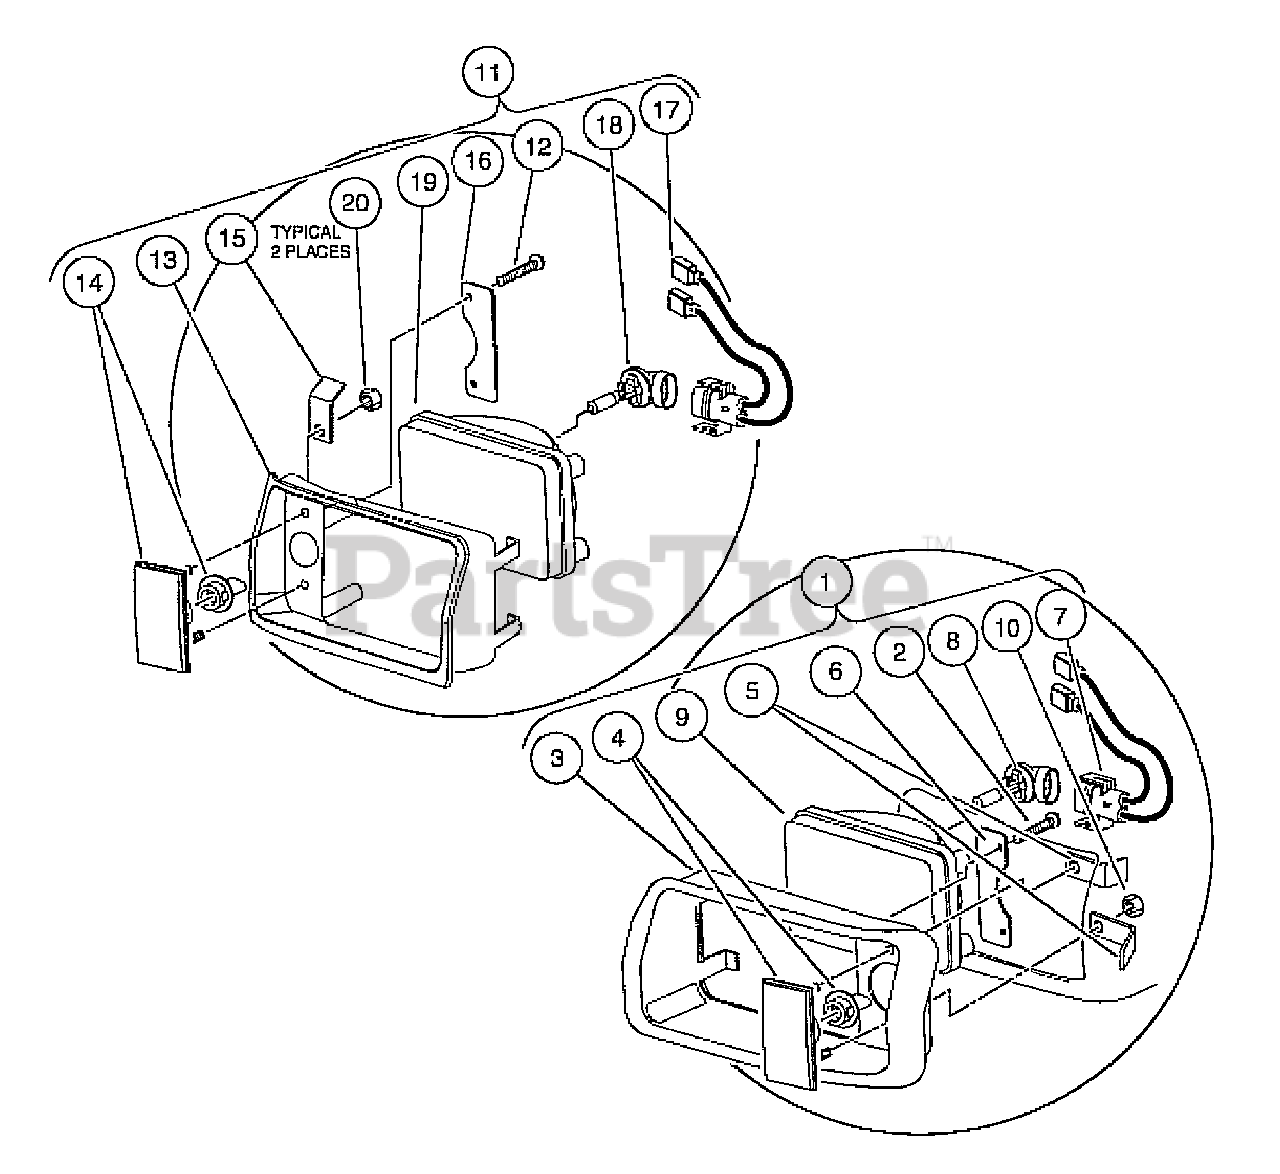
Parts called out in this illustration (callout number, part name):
1	Headlight Assembly, Driver-Side Single Beam
2	Screw, #10-16 Hex Head Hi-lo
3	Headlight Bezel, Left
4	Turn Signal Lens Assy
5	Mounting Bracket
6	Retainer, Headlight
7	Connector Harness Assembly, Headlight
8	Bulb, Headlight
9	Lens, Headlight
10	Nut, #10-32 Hex
11	Headlight Assy, Passenger-Side Single Beam
12	Screw, #10-16 Hex Head Hi-lo
13	Headlight Bezel, Right
14	Turn Signal Lens Assy
15	Mounting Bracket
16	Retainer, Headlight
17	Connector Harness Assembly, Headlight
18	Bulb, Headlight
19	Lens, Headlight
20	Nut, #10-32 Hex
